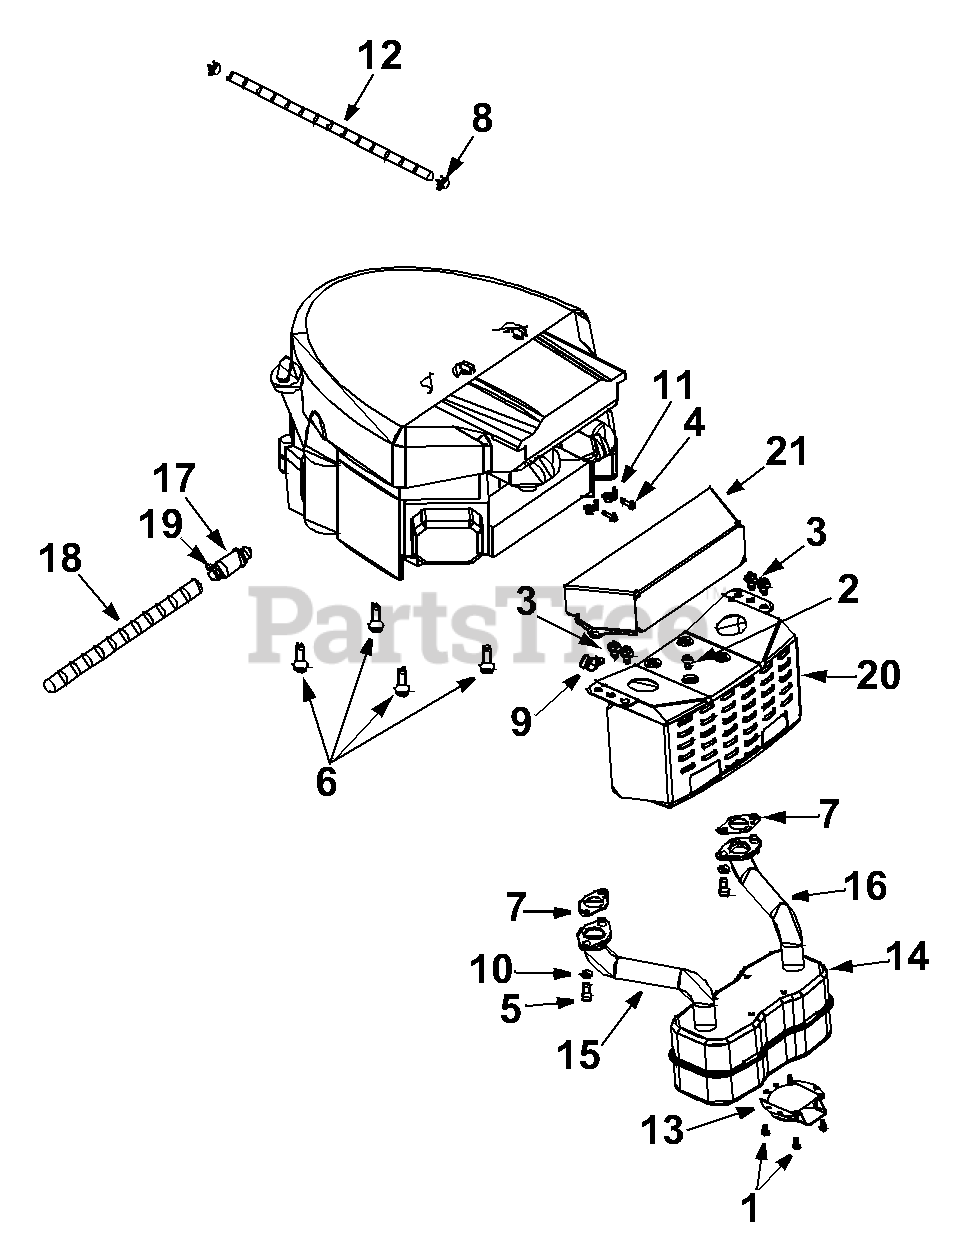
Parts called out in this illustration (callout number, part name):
1	Hex Tap Scr. #8-32 x .38" Lg.
2	Hex Wash. TT-Tap Scr. 1/4-20 x 5" Lg.
3	Hex Wash. TT-Tap Scr. 5.16-18 x .62"
4	Screw
5	Socket Head Scr. 5.16-18 x .62"
6	Hex TT-Tap Scr. 3.8-16 x 1.25"
7	Exhaust Gasket
8	Hose Clamp
9	Clamp
10	Lock Washer 5/16 I.D.
11	Casing Clamp
12	Fuel Line Hose
13	Muffler Deflector
14	Muffler
15	Exhaust Pipe-R.H.
16	Exhaust Pipe-L.H.
17	Oil Drain
18	Oil Drain Hose Extension
19	Oil Drain Cap
21	Heat Shield
